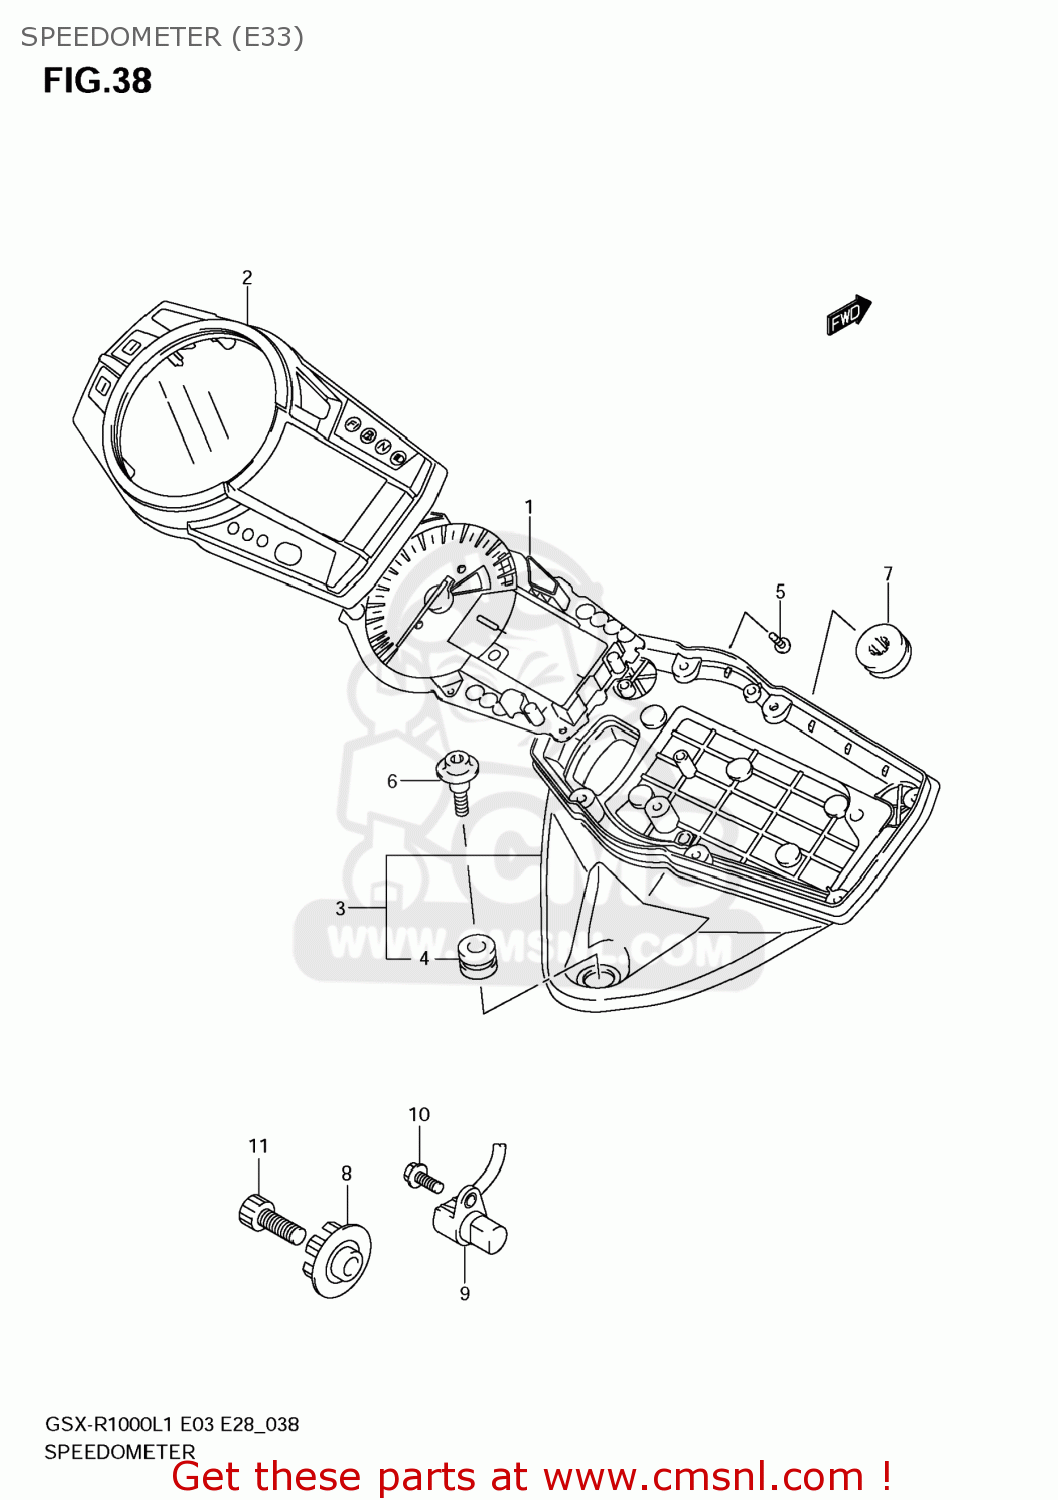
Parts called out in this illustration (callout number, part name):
1	COMBINATION METER
2	CASE ASSY,UPR
3	CASE ASSY,LWR
4	CUSHION,METER
5	SCREW(3X16)
6	SCREW,SPEEDOMETER
7	CUSHION
8	ROTOR,SPEED
9	SENSOR,SPEED
10	BOLT
11	BOLT
